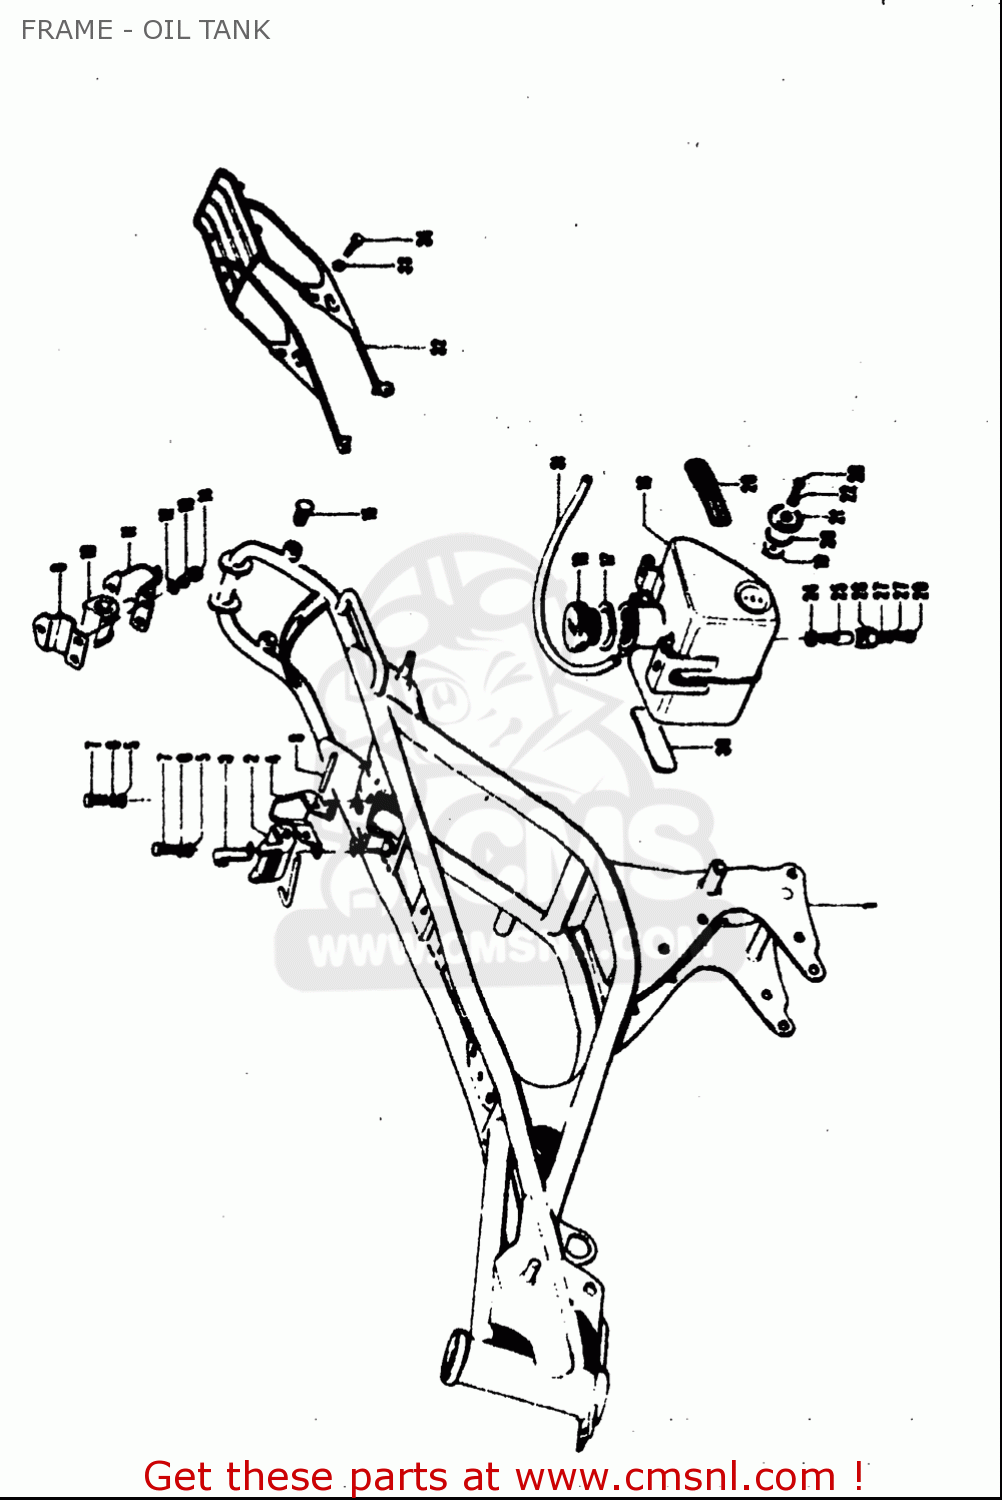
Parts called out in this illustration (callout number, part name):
5	WASHER
6	WASHER,LOCK
12	WASHER
13	WASHER,LOCK
14	NUT
15	CAP(OD:14)
17	GASKET,OIL TANK FILLER CAP (NAS)
18	CAP,OIL TANK
19	LENS SET,OIL INSPECTION
20	O RING(D:3,ID:23)
22	GASKET(5X9.5X1) (NAS)
23	SCREW
24	GASKET,OIL OUTLET JOINT (NAS)
25	UNIT,OIL FILTER
26	OIL OUTLET JOINT NUT
27	WASHER(6.5X24X1.2)
28	UNION BOLT
33	WASHER,LOCK
34	BOLT
